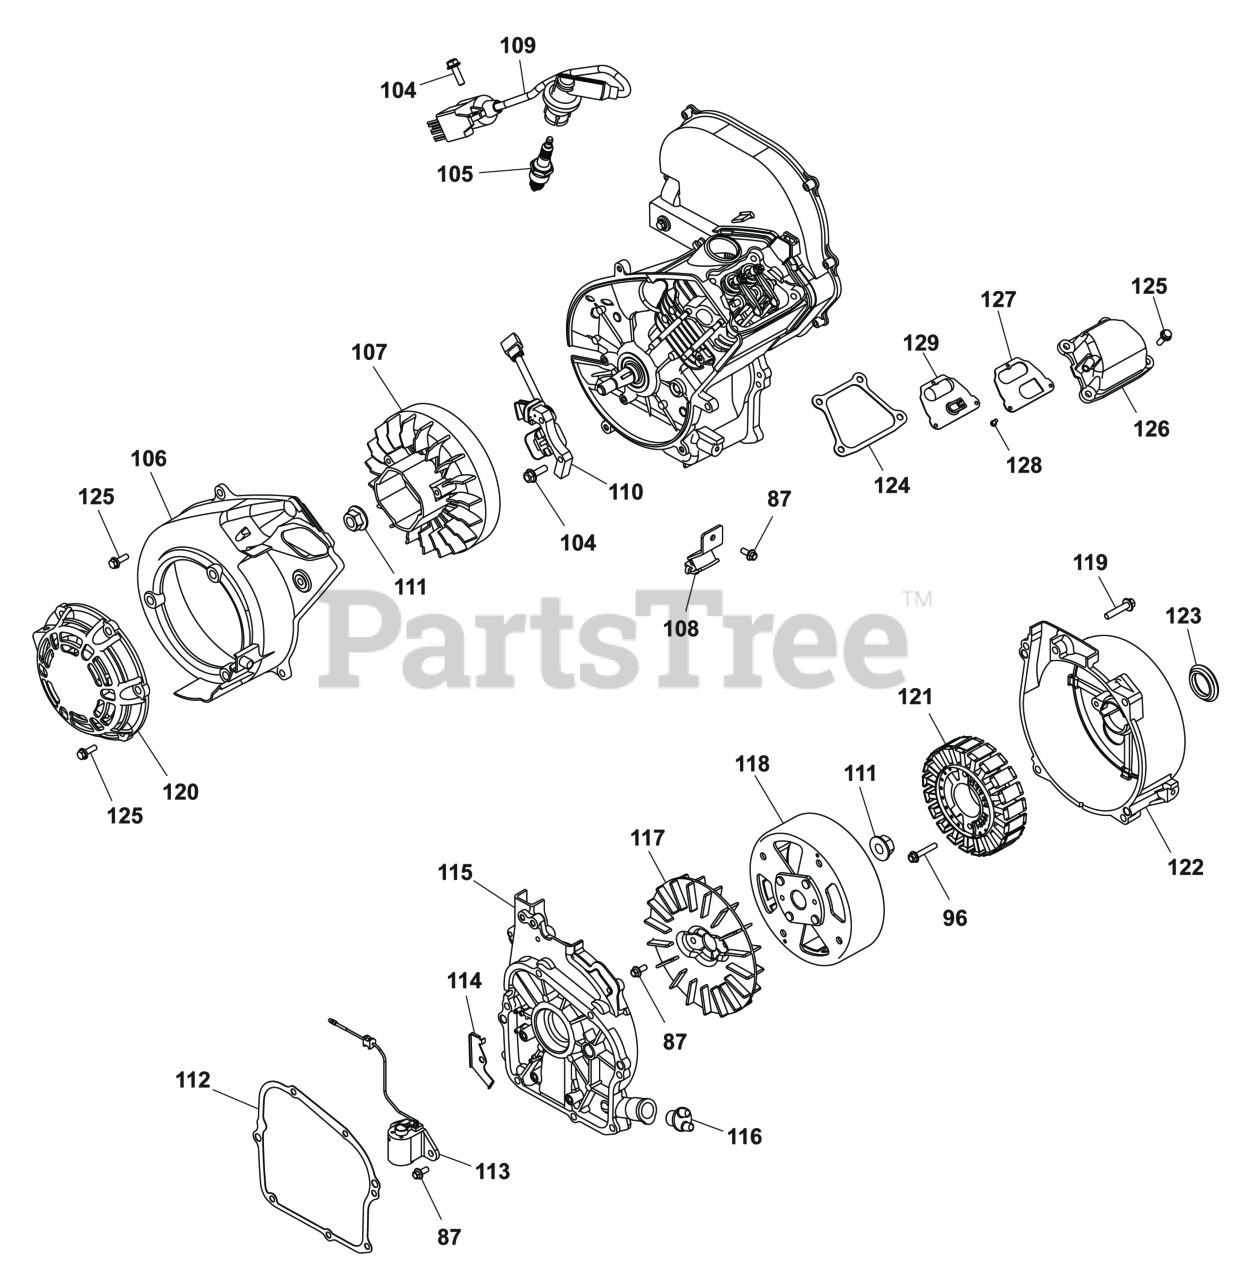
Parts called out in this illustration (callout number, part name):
108	MOUNT-VIBRATION
114	CLAMP
115	COVER, Crankcase
